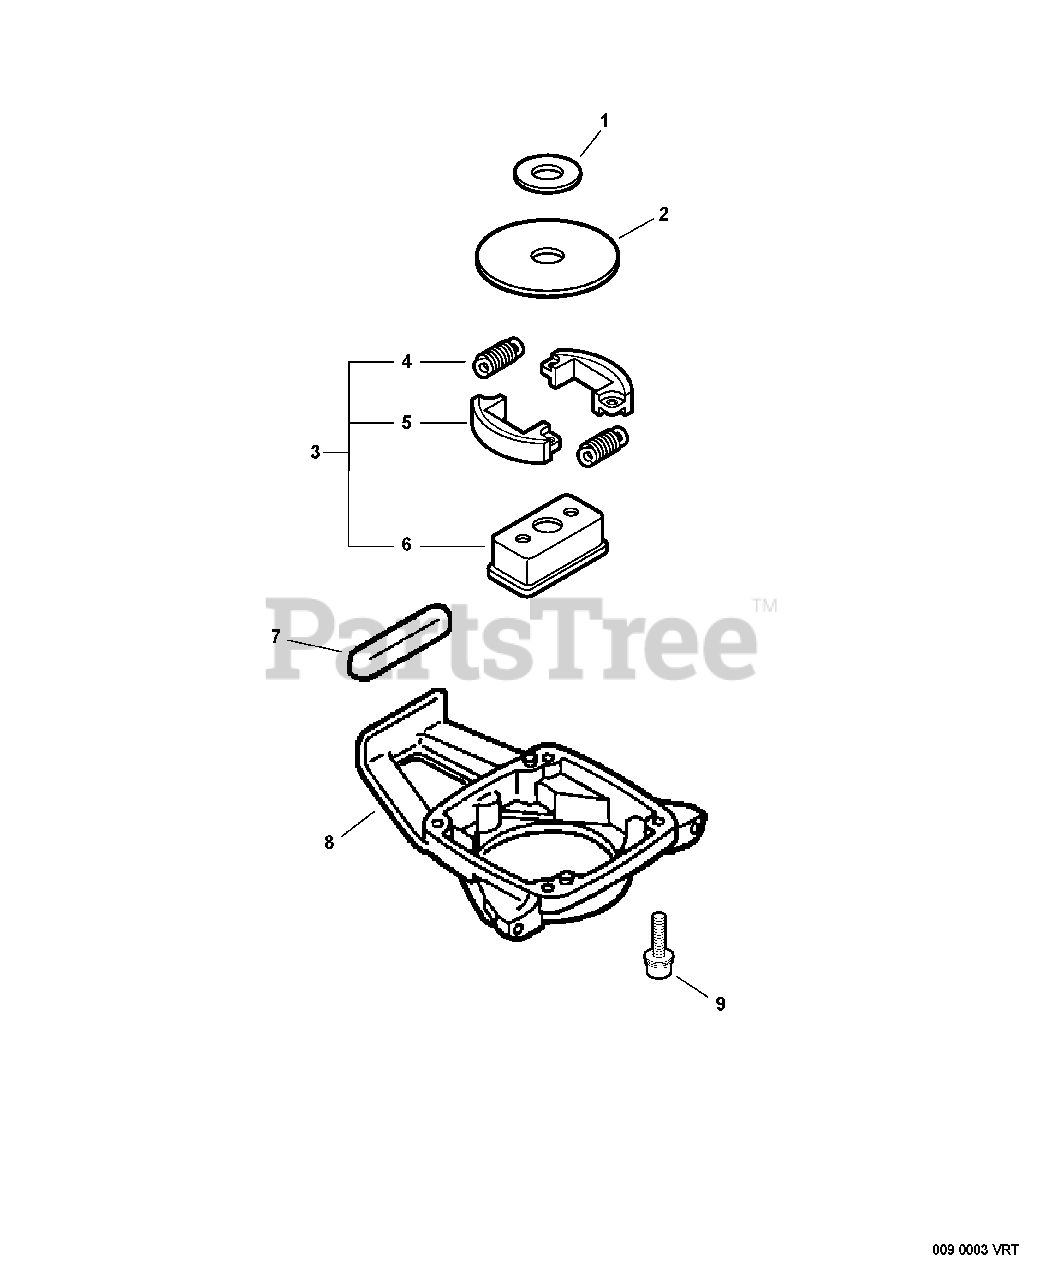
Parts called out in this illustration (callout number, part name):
1	WASHER, CLUTCH
2	PLATE, CLUTCH
3	CLUTCH ASSY
4	SPRING, CLUTCH
5	SHOE, CLUTCH
6	HUB, CLUTCH
7	CUSHION, FUEL TANK
8	CASE, CLUTCH
9	SCREW - 4X16
